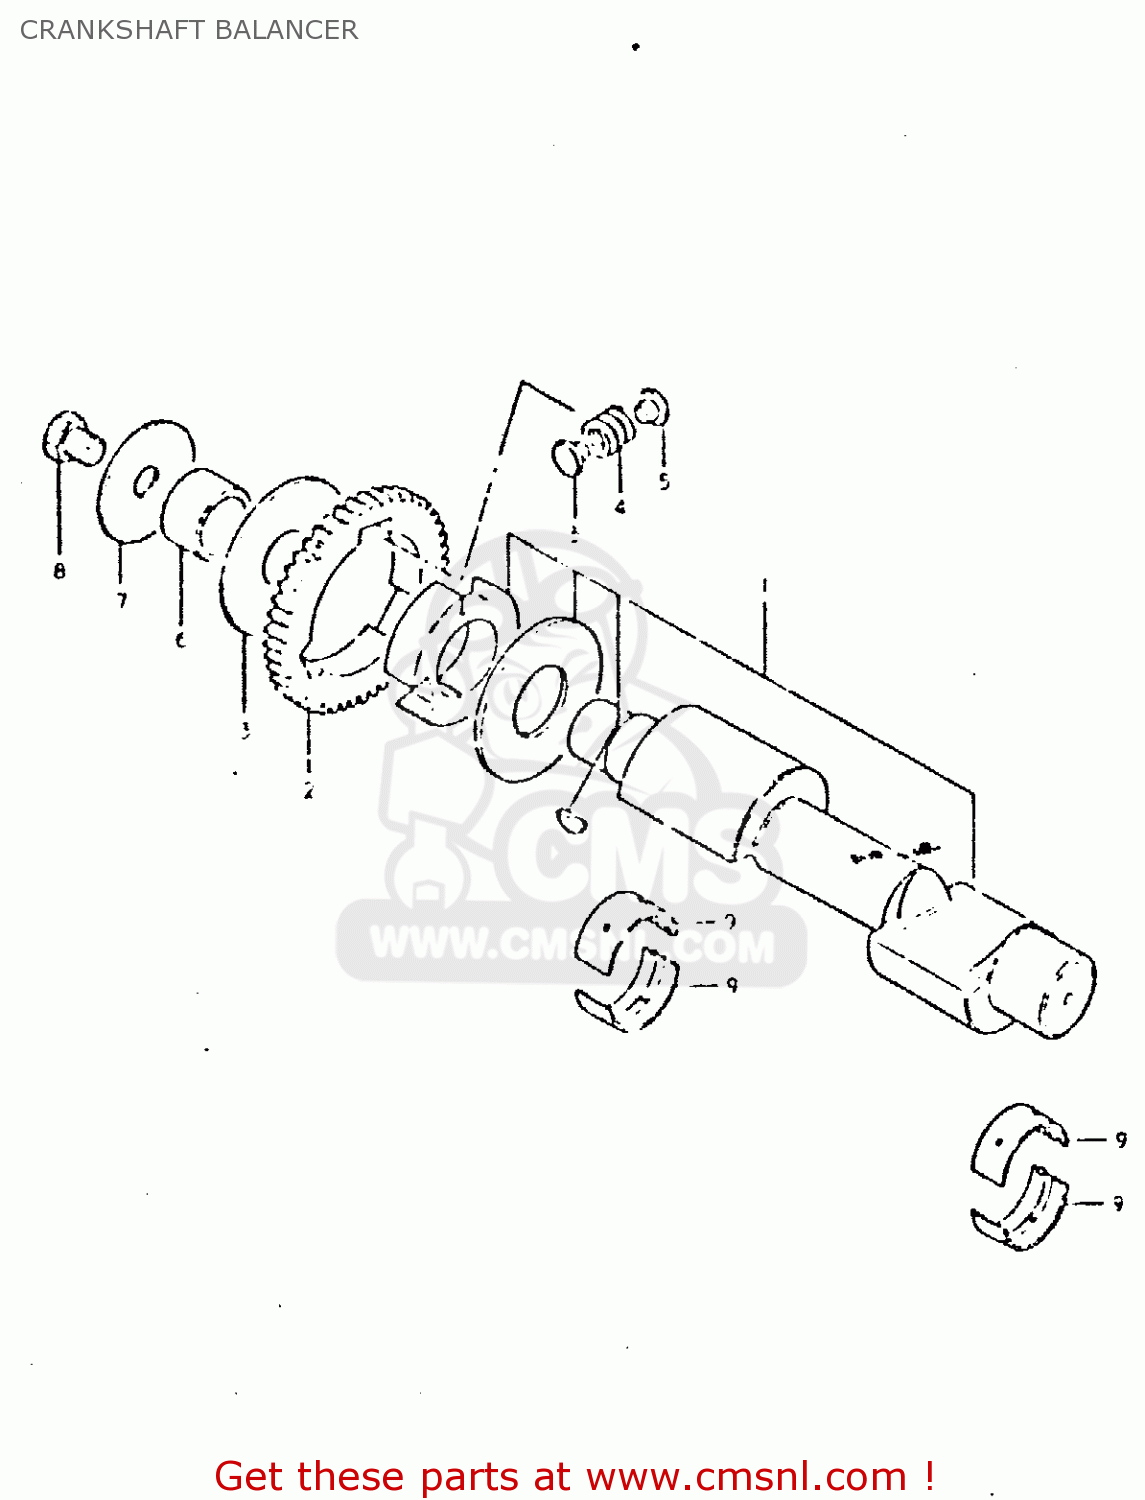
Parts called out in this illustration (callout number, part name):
1	BALANCER,CRANKSHAFT
2	GEAR,CRANK BALANCER DRIVE
3	WASHER
4	SPRING
5	PIN
6	SPACER
7	WASHER(12X50X3)
8	BOLT
9	METAL CRANKSHAFT
